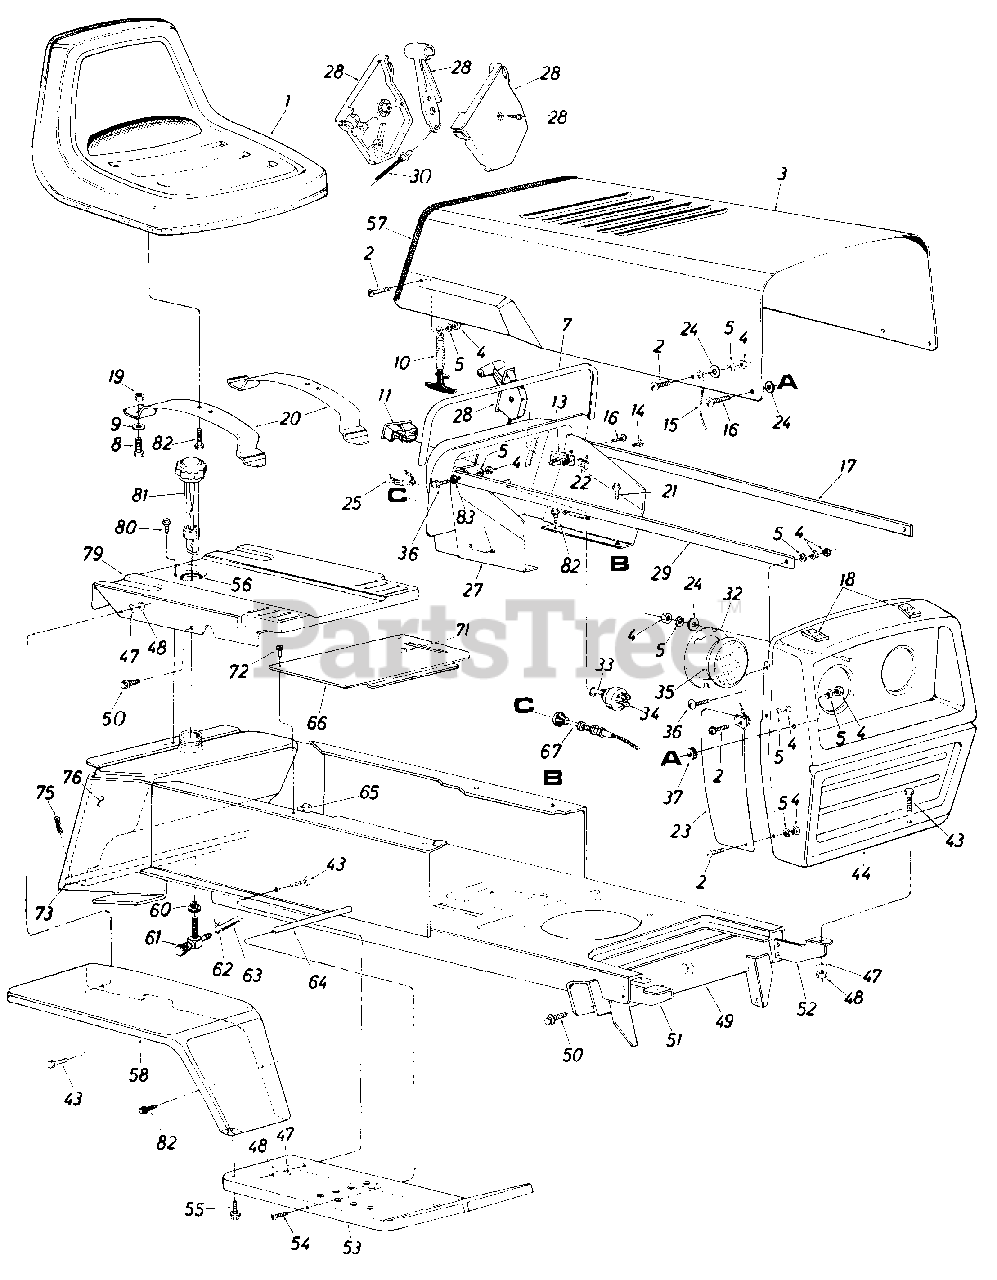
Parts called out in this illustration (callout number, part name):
1	Seat Assembly
2	Truss Mach. Scr. 1/4-20 x .50" Lg.
5	L-Wash. 1/4" Scr.*
7	Vinyl Molding Strip-29"
8	Hex Nylon Scr. 1/2-13 x .75" Lg.
9	Fl-Wash. .50" I.D x 1.00" O.D. x .090
10	Hood Latch Ass'y.
11	Ammeter
13	Circuit Breaker 8 Amp.
14	Hex Tap Scr. #10 x .50" Lg.*
15	Hood Stop
16	Truss Mach. Scr. 1/4-20 x .75" Lg.*
17	Grille Positioning Rod
18	PVC Foam Strip 1/2 x 1.00" x 2.00" Lg.
19	Hex Nut 1/2-13 Thd.
22	Speed Nut #10Z
23	Grille Side Panel-R.H.
24	Fl-Wash. 1/4" I.D.
25	Light Switch
27	Dash Panel Ass'y.
28	Throttle Control Box Comp.
29	Grille Positioning Rod
30	Throttle Control Wire
32	Head Lamp Retainer
33	Ignition Key
34	Ignition Switch
35	Head Lamp
36	Truss Machine Scr. 1/4-20 x .75" Lg.
37	Rubber Wash. .50" I.D. x 1.00 O.D. x .25 Thk.
43	Hex Scr. 5/16-18 x .75" Lg.
44	Grille Ass'y. (Painted)
47	L-Wash. 5/16" Scr.
48	Hex Nut 5/16-18 Thd.
49	Lower Frame Ass'y.
50	Hex Thd. Rolling AB Scr. 5/16 x .75" Lg.
51	Grille Mount Brkt.-R.H.
52	Grille Mount Brkt.-L.H.
53	Running Board-R.H.
54	Truss Mach. Scr. 5/16-18 x .75" Lg.*
55	Hex Thd. Rolling Scr. 5/16-24 x .75" Lg.
56	Grommet
57	Vinyl Moulding Strip-30"
58	Fender Ass'y.-R.H.
60	Bushing
61	90ø Nipple
62	Hose Clamp 3/8"
63	Gas Line 46" Lg.
64	Running Board Rod
65	Speed Nut
66	Transmission Cover Ass'y.
67	Choke Control Comp.
71	Snap Bushing
72	Truss Hd. Scr. 1/4-20 x .75" Lg.
73	Hitch Rod
75	Internal Cotter Pin
76	Gas Tank
79	Seat Plate
80	Hex Thd. Rolling Scr. 5/16-24 x .75" Lg.
81	Gas Gauge
82	Hex Thd. Rolling Scr. 5/16-24 x .75" Lg.
83	External Wash. 1/4" I.D.
